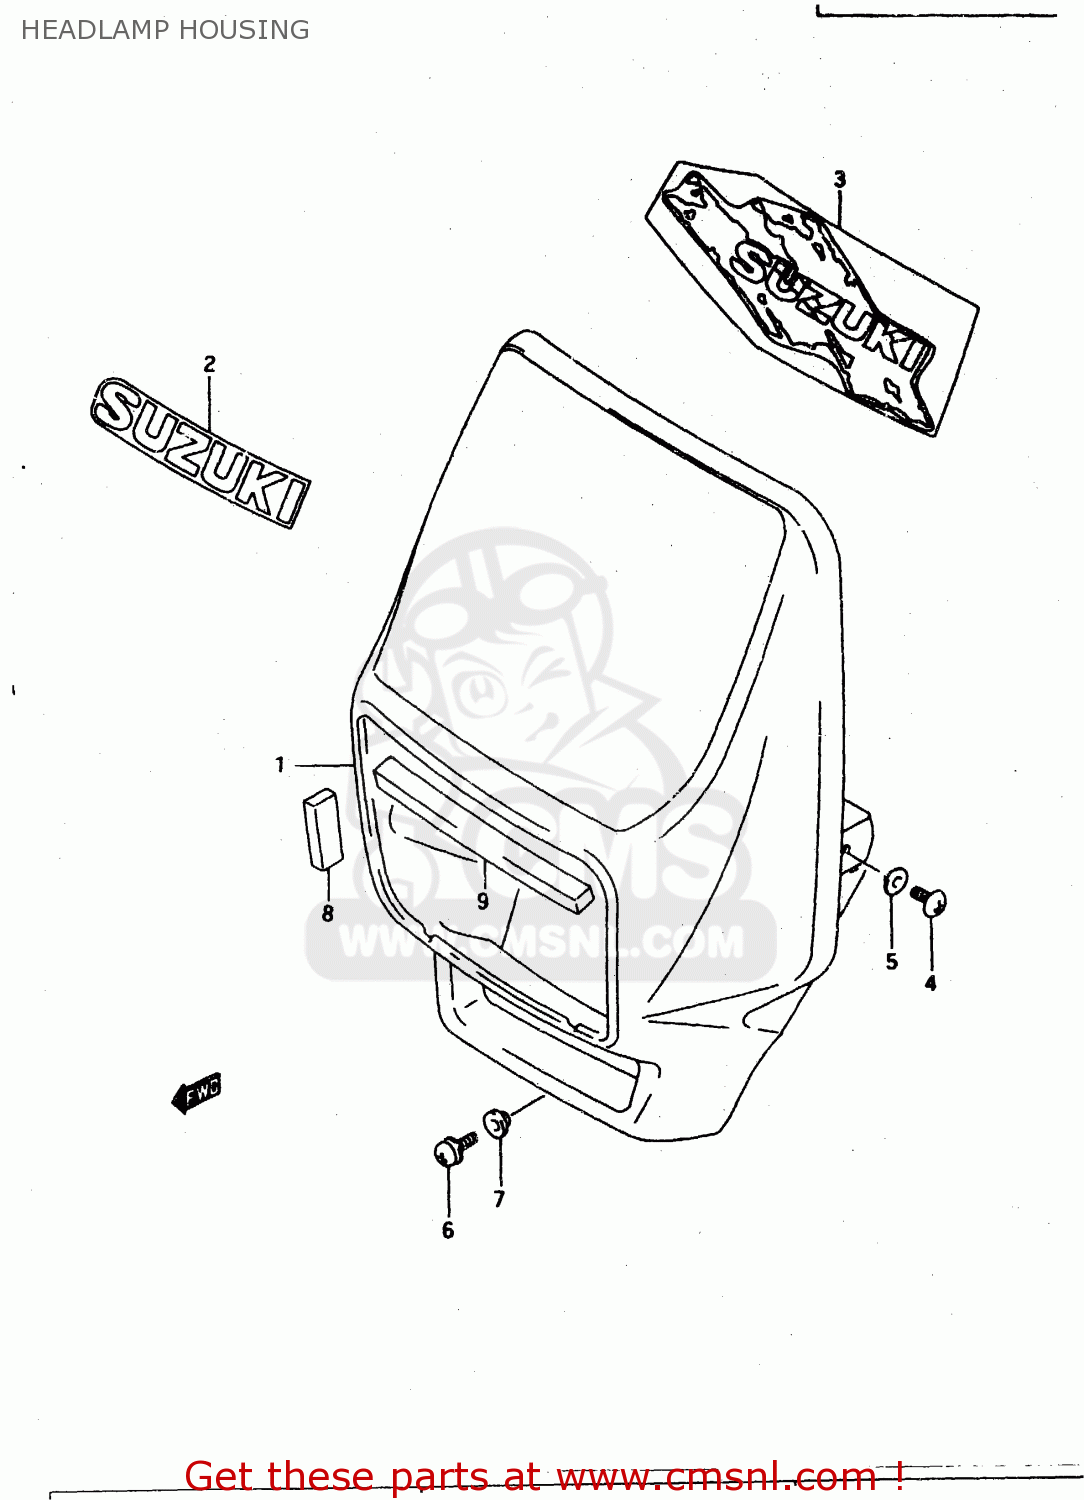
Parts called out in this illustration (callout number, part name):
1	COVER,HEADLAMP
2	EMBLEM, SUZUKI
3	TAPE,HEADLAMP COVER
4	SCREW 6X12
5	WASHER
6	SCREW
7	WASHER(5.2X14X1.5)
8	CUSHION,HEADLAMP COVER
9	CUSHION,HEADLAMP COVER SIDE
